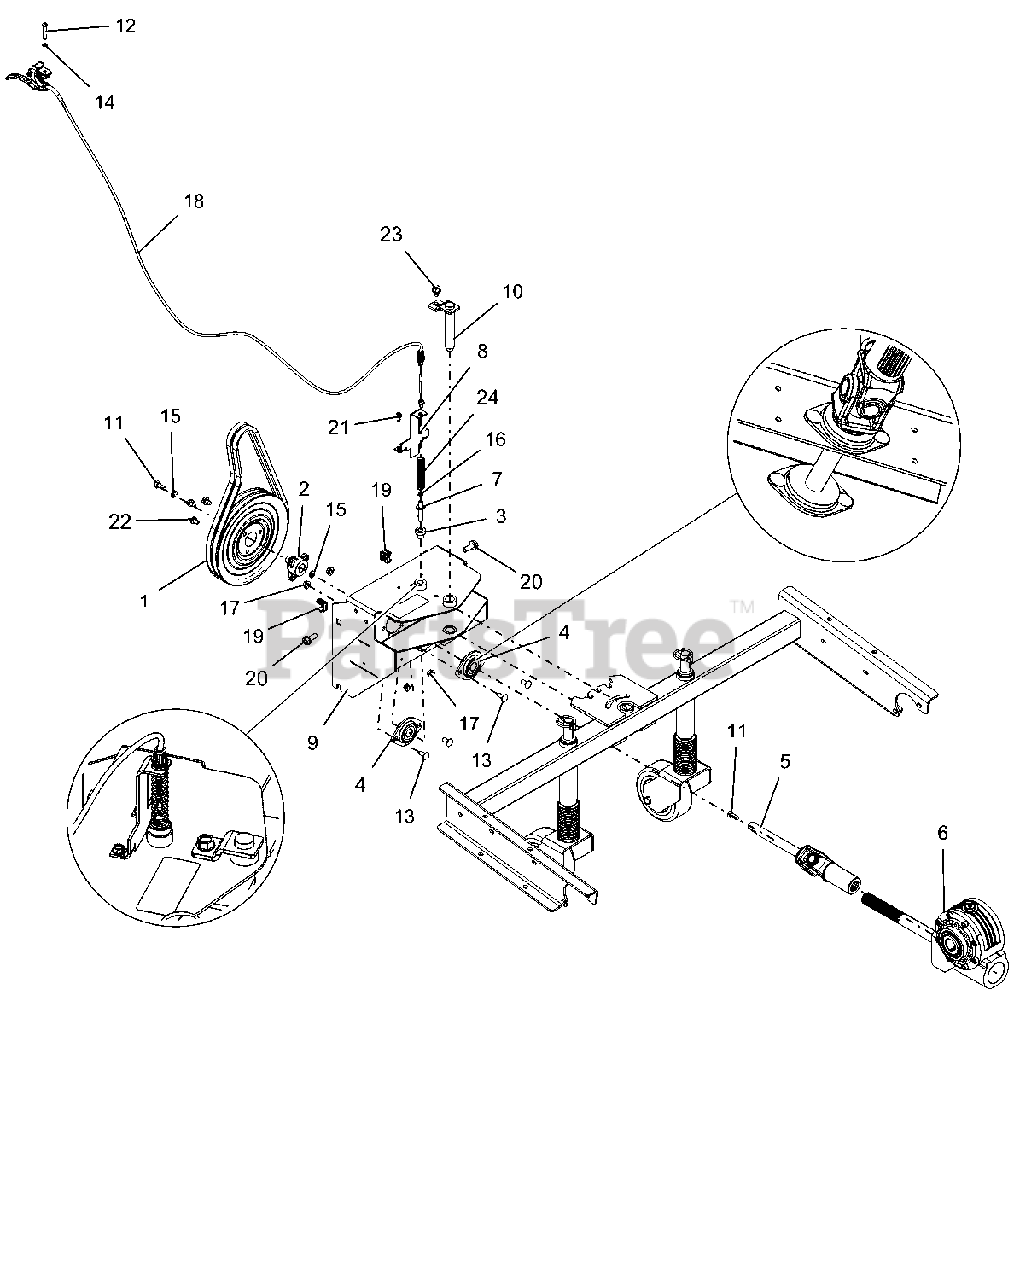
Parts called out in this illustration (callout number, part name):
1	PULLEY, SPIN FORM DUAL GROOVE
2	PULLEY HUB, BOLT-ON D-BORE .75
3	SPACER -FLANGED .390X.500X.781
4	BEARING, 2 BOLT FLANGE -.75 ID
5	DRIVELINE, SERIES 07 (U-JOINT)
6	GEARBOX, WORM - 8.25:1
7	PIN, ADJUSTABLE ANGLE BRUSH
8	BRKT, PIN HOLDER
9	ADAPTER, BRUSH
10	WLDMT, BRUSH PIN
11	BLT-HEX .31-24X.75 YWZC GR5
12	SCR-MCH .25-20X1.50 OVAL HD
13	BLT-RDHDSQNK .31-18X.75 G5YZ
14	WSHR-LK-INT .250 TH TYA
15	WSHR-LK .312X.097 HVY YWZC
16	NUT-HEX 10-24 YWZC
17	NUT-LK-TOP-FLG .31-18 YWZC
18	CABLE, REMOTE BRUSH LOCK
19	NUT-RETNR .38-16 TINRMAN
20	BLT-SERHFWH .375-16X1.0 YWZC
21	SCR-TAP .25-20X.50 HWH TR YWZ
22	SCR-TAP .31-18X.50 HWH TR YWZ
23	SCR-TAP .38-16X.50 HWH TR YWZ
24	SPRING, COMPRESSION
